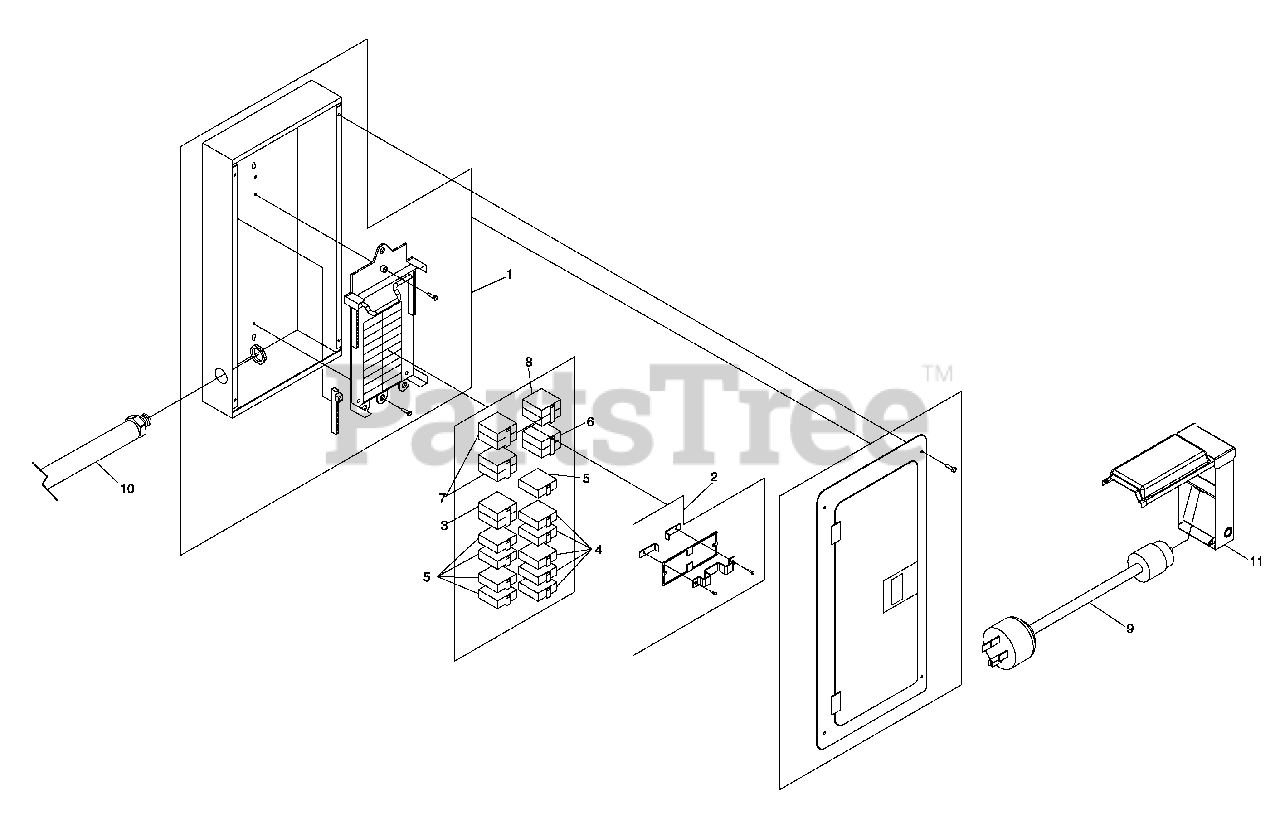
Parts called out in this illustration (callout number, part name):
1	BOX LOAD CENTER W/HARDWARE
2	CIRCUIT BREAKER INTERLOCK
3	CIRCUIT BREAKER 20A 2P
4	CIRCUIT BREAKER 15A 1P
5	CIRCUIT BREAKER 20A 1P
6	CIRCUIT BREAKER 40A 2P
7	CIRCUIT BREAKER 50A 2P
8	CIRCUIT BREAKER 60A 2P
9	HARNESS, 50 AMP PLUGS
10	HARNESS, LOAD CENTER TO MAIN PANEL
11	POWER INLET BOX
